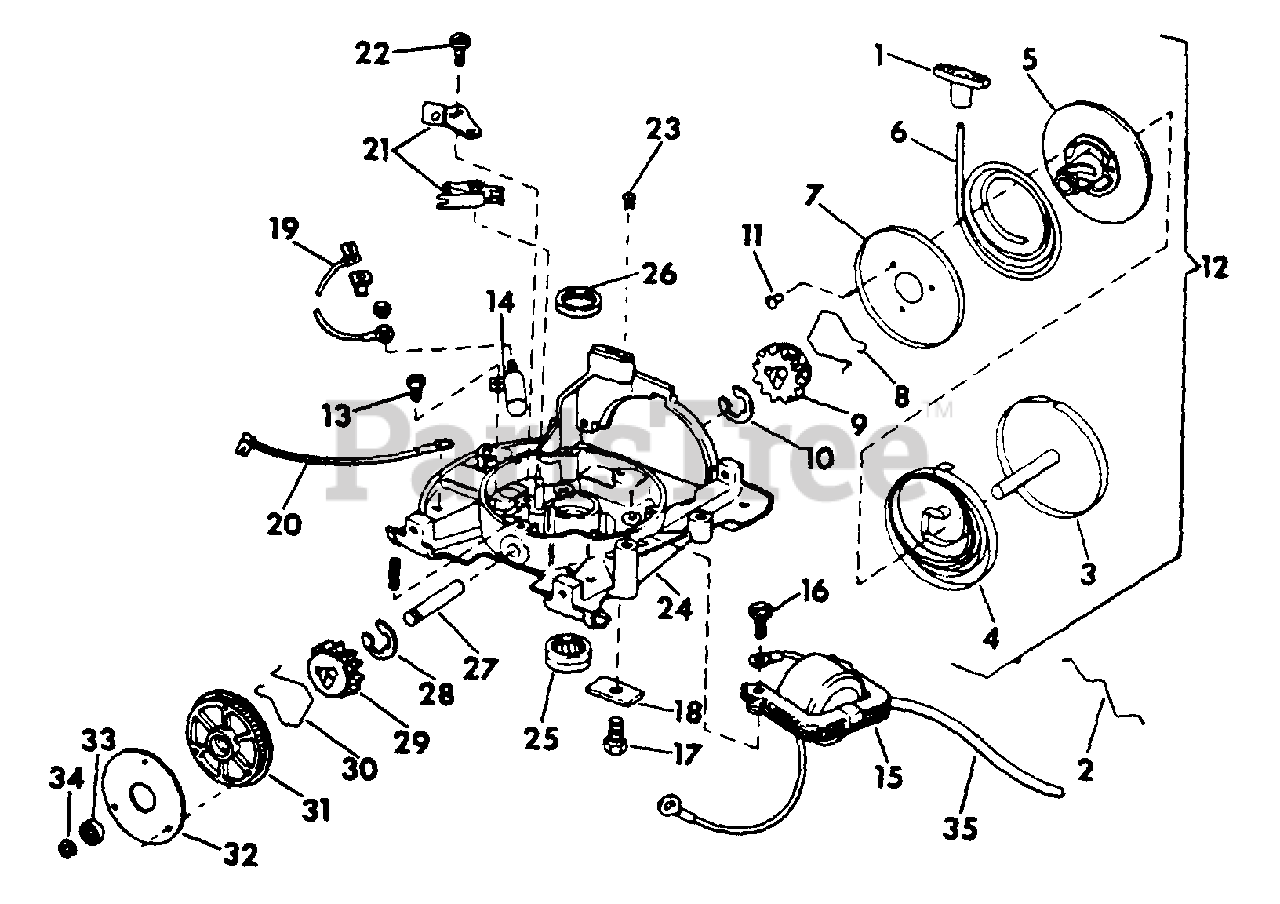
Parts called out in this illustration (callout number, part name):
1	HANDLE, STARTER
2	SPRING, STARTER ROPE RETAINER
3	SPRING, CUP & PIN
4	SPRING, STARTER
5	PULLEY, STARTER
6	ROPE, STARTER - 53 IN.
7	PLATE, STARTER PULLEY
8	SPRING, STARTER PINION
9	PINION, STARTER
10	RING, RETAINER
11	SCREW, THD CUTTING STARTER
12	STARTER ASSY
13	SCREW, CONDENSER MTG
14	CONDENSER & NUT ASSY
15	COIL & LAMINATION ASSY
16	SCREW, LAMINATION MTG
17	SCREW, STARTER ATT
18	CLAMP, STARTER PIN
19	TERMINAL & LEAD ASSY
20	TERMINAL & LEAD ASSY
21	BREAKER BASE & ARM
22	SCREW, BREAKER BASE
23	GROMMET, COVER MTG
24	ARMATURE PLATE BRG & SEAL ASSY
27	SHAFT, STARTER
28	RING, RETAINING
29	PINION, STARTER
30	SPRING, STARTER PINION
31	PULLEY, STARTER
32	PLATE, STARTER PULLEY
33	BEARING, STARTER PULLEY NEEDLE
34	RING, STARTER SHAFT RETAINING
35	HIGH TENSION LEAD ASSY
